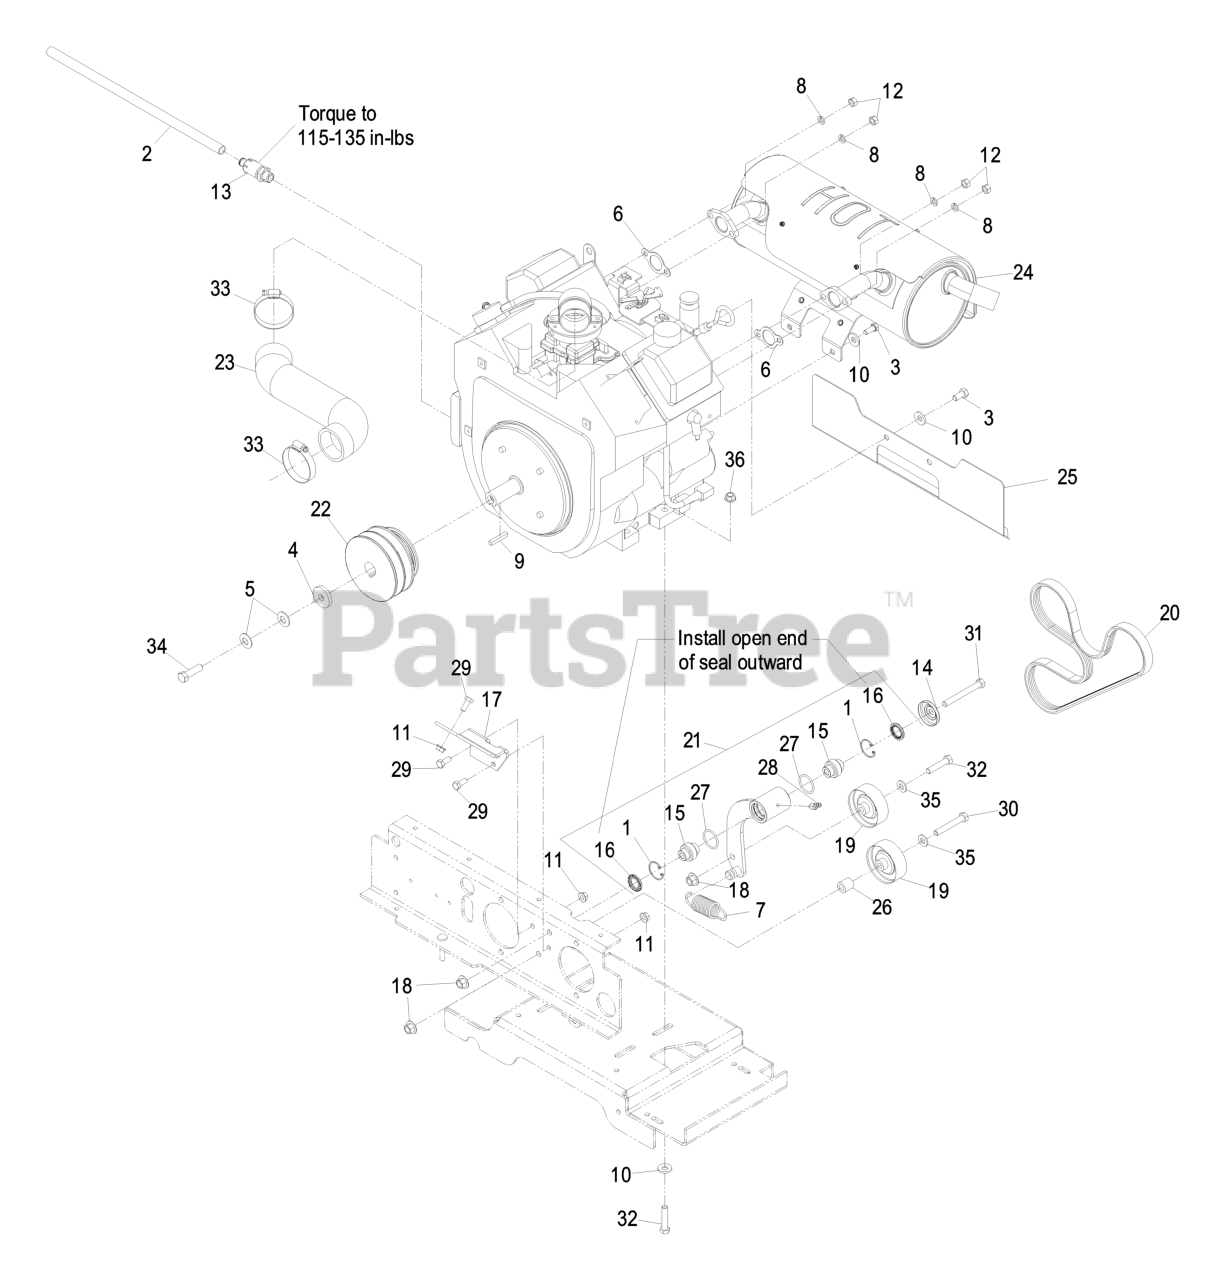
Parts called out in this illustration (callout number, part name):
1	RING-SNAP
2	TUBE-DRAIN, OIL
3	SCREW-HH
4	WASHER-CLUTCH
5	WASHER-SPRING
7	SPRING-IDLER
8	WASHER-LOCK
9	KEY-SQUARE
10	WASHER-BELLEVILLE
12	NUT-HEX
13	VALVE-DRAIN, OIL
14	GUARD-TOP
15	BEARING-SPHERICAL
16	SEAL-LIP, SINGLE
17	BRACKET-FILTER, AIR
18	NUT-FLANGE
20	BELT-V
21	IDLER ASM
23	HOSE-AIR INTAKE
25	SHIELD-EXHAUST
26	SPACER-MOUNTING, STEERING
28	FITTING-LUBE, 45 DEG
29	SCREW-HH
30	BOLT-CARR
31	SCREW-HH
32	SCREW-HH
34	SCREW-HH
35	WASHER-FLAT
36	NUT-HHF, WHIZ
